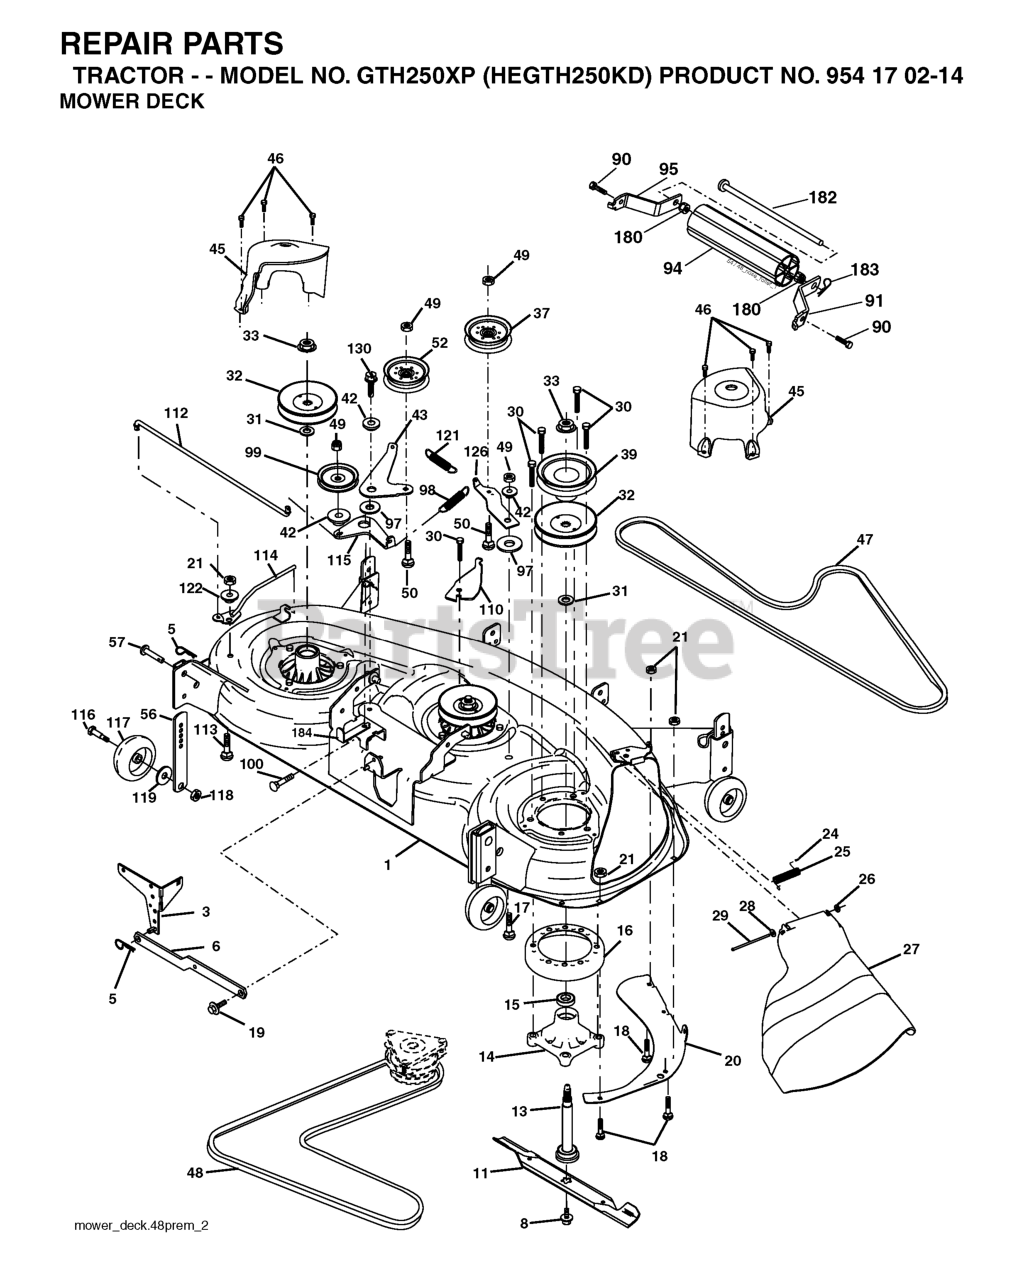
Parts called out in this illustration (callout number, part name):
1	DECK WELDMENT
3	BRACKET ASM.
5	RETAINER-SPRNG RB
6	BAR SWAY DECK
8	BOLT 7/16 ASM BLADE
11	48" HI-LIFT BLADE
13	SHAFT ASM W/LOWER BEARING
14	HOUSING, MANDREL 48"
16	STRIPPER.MANDREL.ROUND.BLACK
17	BOLT
18	BOLT
19	BOLT SHD 5/16-18
20	BAFFLE, VORTEX MWR
21	LOCKNUT
24	CAP-SLEEVE LT
25	SPRING, TORSION
26	NUT PUSH M
27	DEFLECTOR SUBS TO 532 180655
28	Washer 11/32 x 5/8 x 16 Ga SD
29	ROD.HINGE
30	SCREW, WASHER HEAD
31	WASHER.SPACER.MANDREL
32	PULLEY MANDREL
33	NUT, FLG TOPLOCK 9/16"
37	PULLEY.IDLER.FLAT
39	PULLEY.DRIVEN.DECK.48'
42	SPACER.RETAINER.MOWER
43	ARM, IDLER SECONDARY
45	COVER.MANDREL.DECK.48"
46	SCREW.1/4-20X5/8
47	V-BELT, 48"SECONDARY
48	V-BELT PRIMARY 48"
49	NUT LOCK FLG 3/8-16 UNC
50	BOLT.3/8-16X1.50
52	PULLEY.IDLER.FLAT.46.PR.DR.
56	BAR.ADJUST.WHEEL.ANTI.SCALP.BL
57	RIVET.PIN.HEAD.YELLOW.
90	BOLT RB
91	BRKT.NOSEROLLER.RH.48"
94	NOSE ROLLER 48"
95	BRKT.NOSEROLLER.LH.48"
98	SPRING PRIMARY DRIVE
99	IDLER PULLEY
110	ARM, SPRING SECONDARY
112	LEVER, TENSION RELIEF LINK
113	BOLT.CARR.SQNK.5/16-18UNC.X3/4
114	LEVER ASM, TENSION RELIEF
115	ARM, SPRING TENSION RELIEF
116	SHOULDER BOLT
117	RP WHEEL. GUAGE RALLY
118	LOCKNUT
119	WASHER.5/16.FLAT.STE.STD.
121	SPRING.DRIVE.SECONDARY.48".DEC
122	BUSHING, PIVOT TENSION RELIEF
126	ARM, IDLER PRIMARY DECK
130	SCREW 3/8-16X1
180	NUT.71038.31-18.HEX.NYLOCK
182	ROD.ROLLER.NOSE.NARROW.48"
183	SPRING RETAINER
184	KEEPER BELT IDLER PLATED
